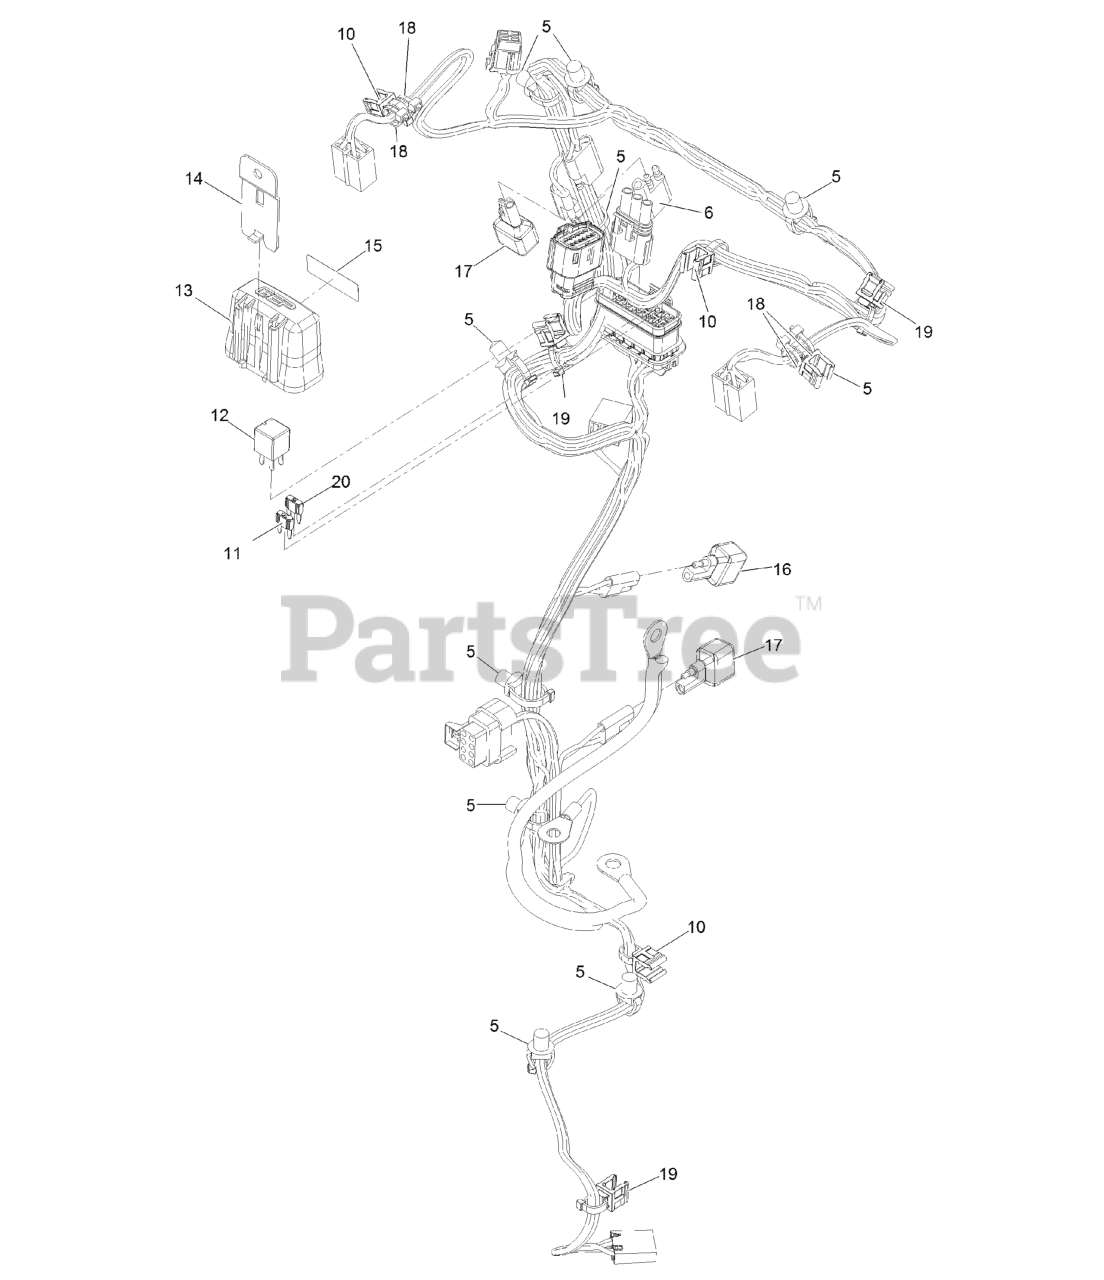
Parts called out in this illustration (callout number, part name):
5	CLIP-TIE
6	Cap-Plug
10	Clip-Edge
11	FUSE-MINI BLADE, 20 AMP
12	RELAY-MICRO
13	COVER-BLOCK, FUSE
14	CLIP-MOUNTING
15	DECAL-FUSE
18	TIE-CABLE
19	Clip-Edge W/Tie, Perpendicular
20	FUSE-MINI BLADE, 15 AMP
